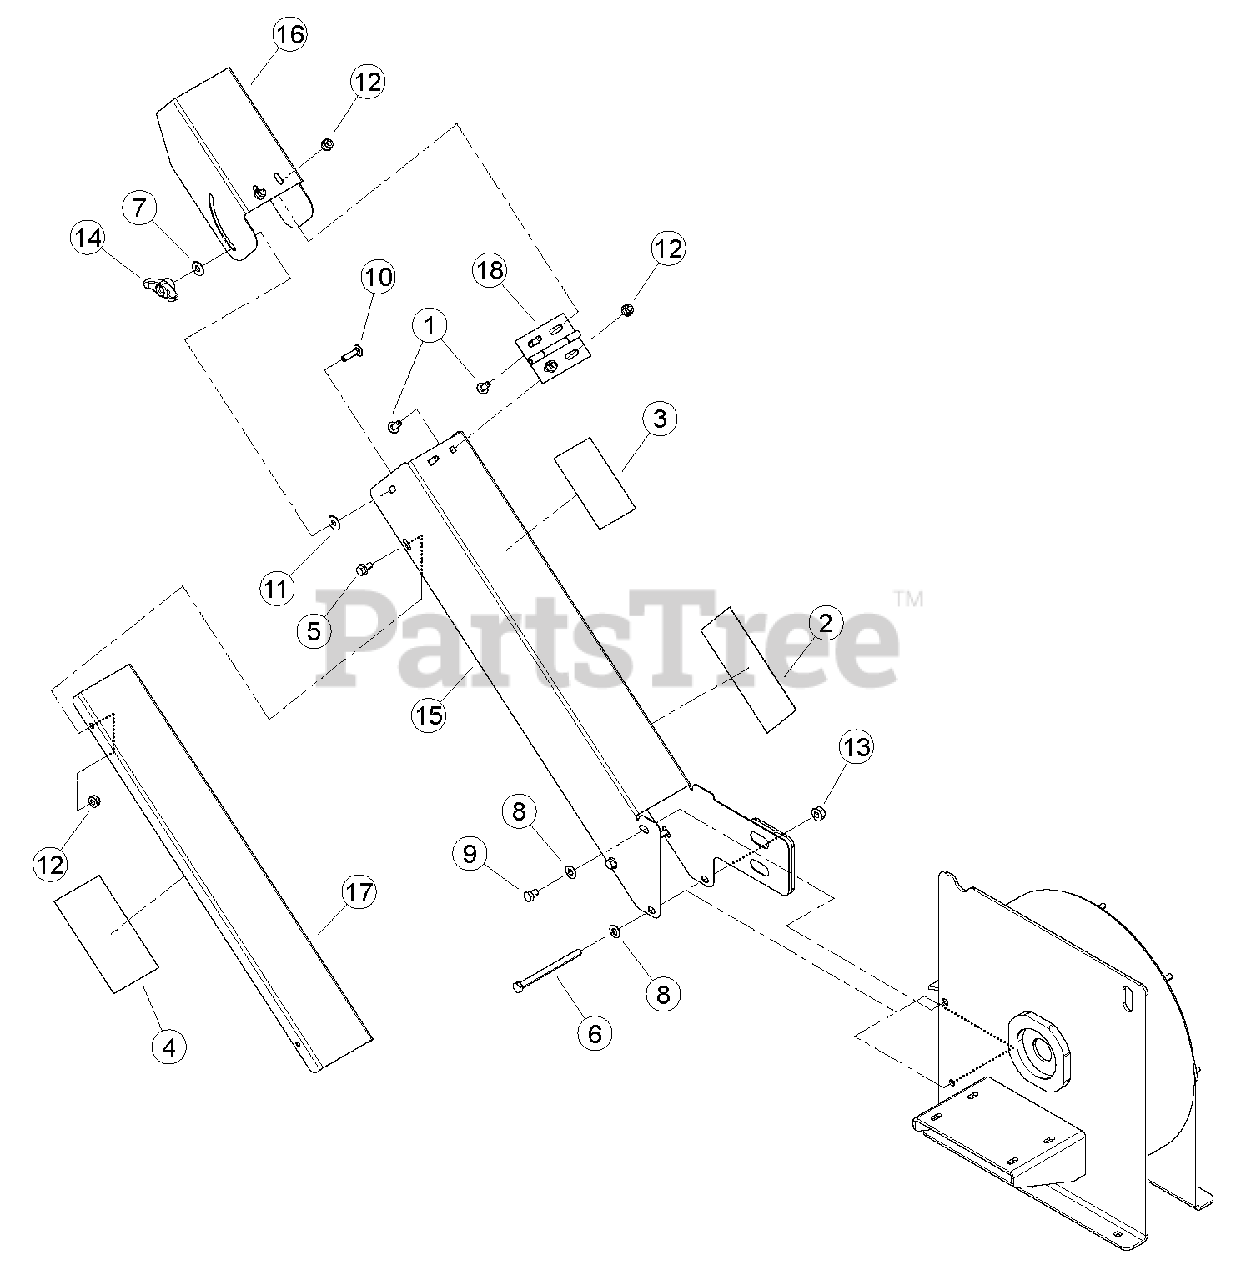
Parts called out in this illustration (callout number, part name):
1	BOLT, 5/16-18 X 3/4 SN GR5 CRG
2	DECAL, KNIFE ACCESS ISO
3	DECAL, DISCHARGE ISO
4	DECAL, BLADE DANGER ISO
5	BOLT, 5/16 X 5/8 FLANGE NC
6	BOLT, 3/8 X 5" GR5 HEX CPS ZP
7	WASHER, 5/16 FLAT
8	WASHER, 3/8 SAE FLAT ZP
9	BOLT, 3/8 X 1/2 GR5 HEX CPS ZP
10	BOLT, 5/16 X 1-1/4 GR5 CRG
11	WASHER, 5/16" ID 7/8" OD NYLON FLAT
12	NUT, 5/16-18 NYLOCK FLANGE
13	NUT, 3/8-16 NYLOCK FLANGE
14	KNOB, 5/16-18 UNC TEE W/ LOCKING INSERT
15	WELDMENT, CHIPPER DISCHARGE
16	CAP, DISCHARGE
17	PLATE, DISCHARGE CHUTE
18	HINGE, DISCHARGE CAP
